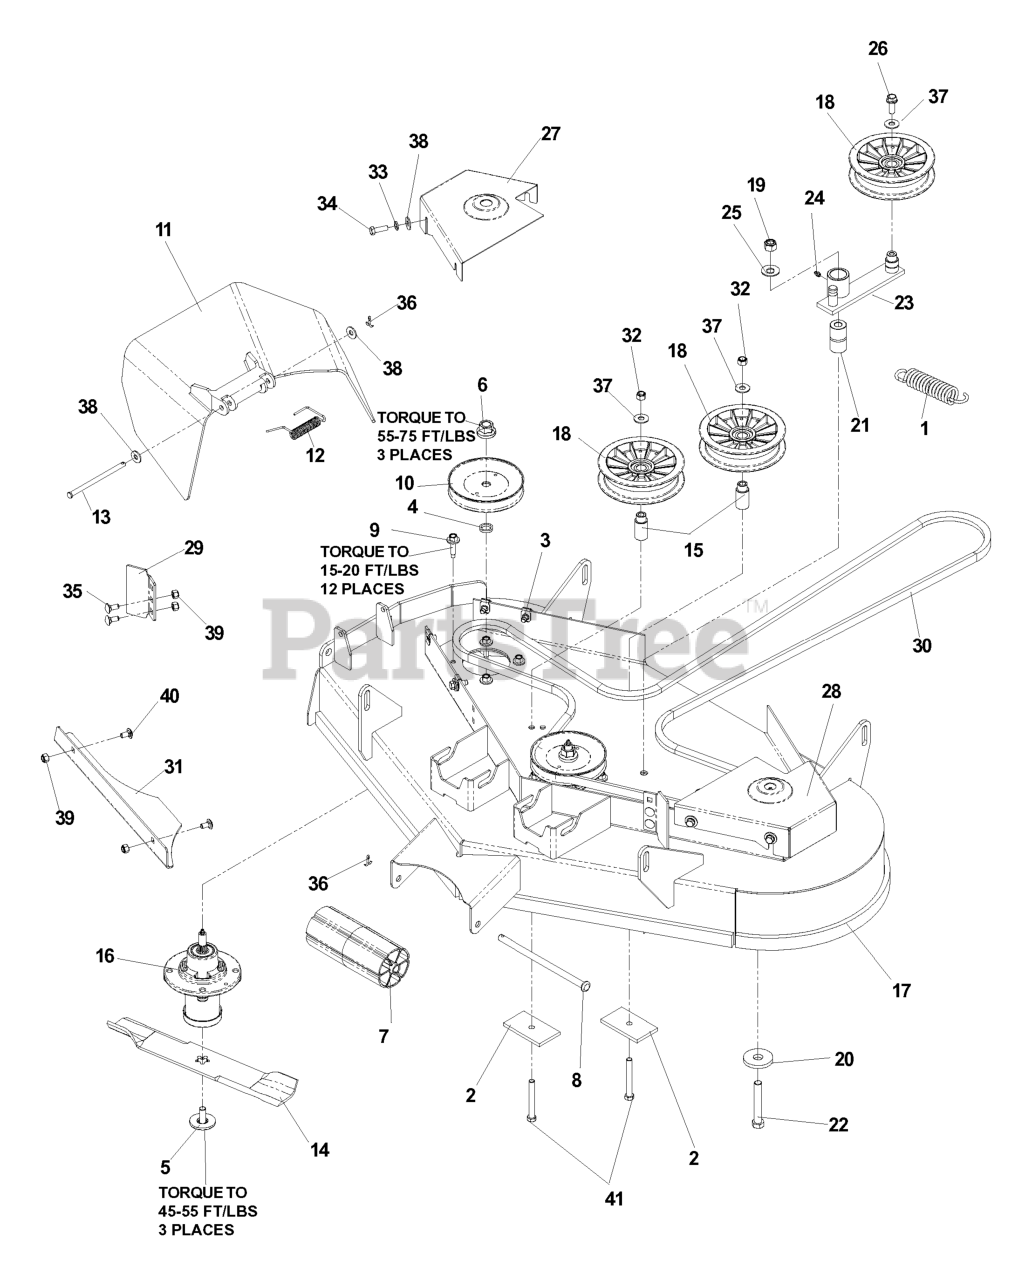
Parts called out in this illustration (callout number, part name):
2	SUPPORT PLATE
3	U-CLIP 5/16-18 NUT RETAINER
4	WASHER-SPACER
5	BLADE BOLT ASSY-7/16" TB REPL
6	LOCKNUT - 9/16
7	NOSE ROLLER 48"
8	NOSE ROLLER ROD
9	WASHER HEAD SCREW
10	PULLEY MANDREL
11	DISCHARGE CHUTE 42"
12	SPRING - TORSION
13	PIN-CLEVIS 5/16 DIA X 5.19 ZD
14	BLADE, 14 5/8"
15	IDLER BUSHING
16	MANDREL.DECK.ASSEMBLY
17	DECK W/DECALS 42"
18	IDLER
19	NUT 1/2-13 HEX NYLOC ZD
20	WASHER, SUPPORT
21	PIVOT BUSHING
22	HCS 1/2C X 3 1/4
24	ZERK
25	WASHER 1/2 FLAT
26	4CS 3/8C X 1 SERRATED HEAD
27	BELT SHIELD, RIGHT 42, ORG
28	BELT SHIELD, LEFT 42, ORG
30	BELT, DECK 42"
31	CONFINEMENT.PLATE.42".BLACK
32	NUT 3/8-16 NYLOC
33	WASHER.LOCK.HVY.HLCL.SPR.5/16
34	HCS 5/16C X 1
35	BOLT 5/16C X 3/4" CARRIAGE
36	RP_COTTER PIN 1/8 X 3/4
37	WASHER 3/8 FLAT
38	WASHER 5/16 FLAT
39	NUT 5/16 NYLOC
40	CARRIAGE BOLT 5/16C X 5/8"
41	HCS 3/8C X 3
